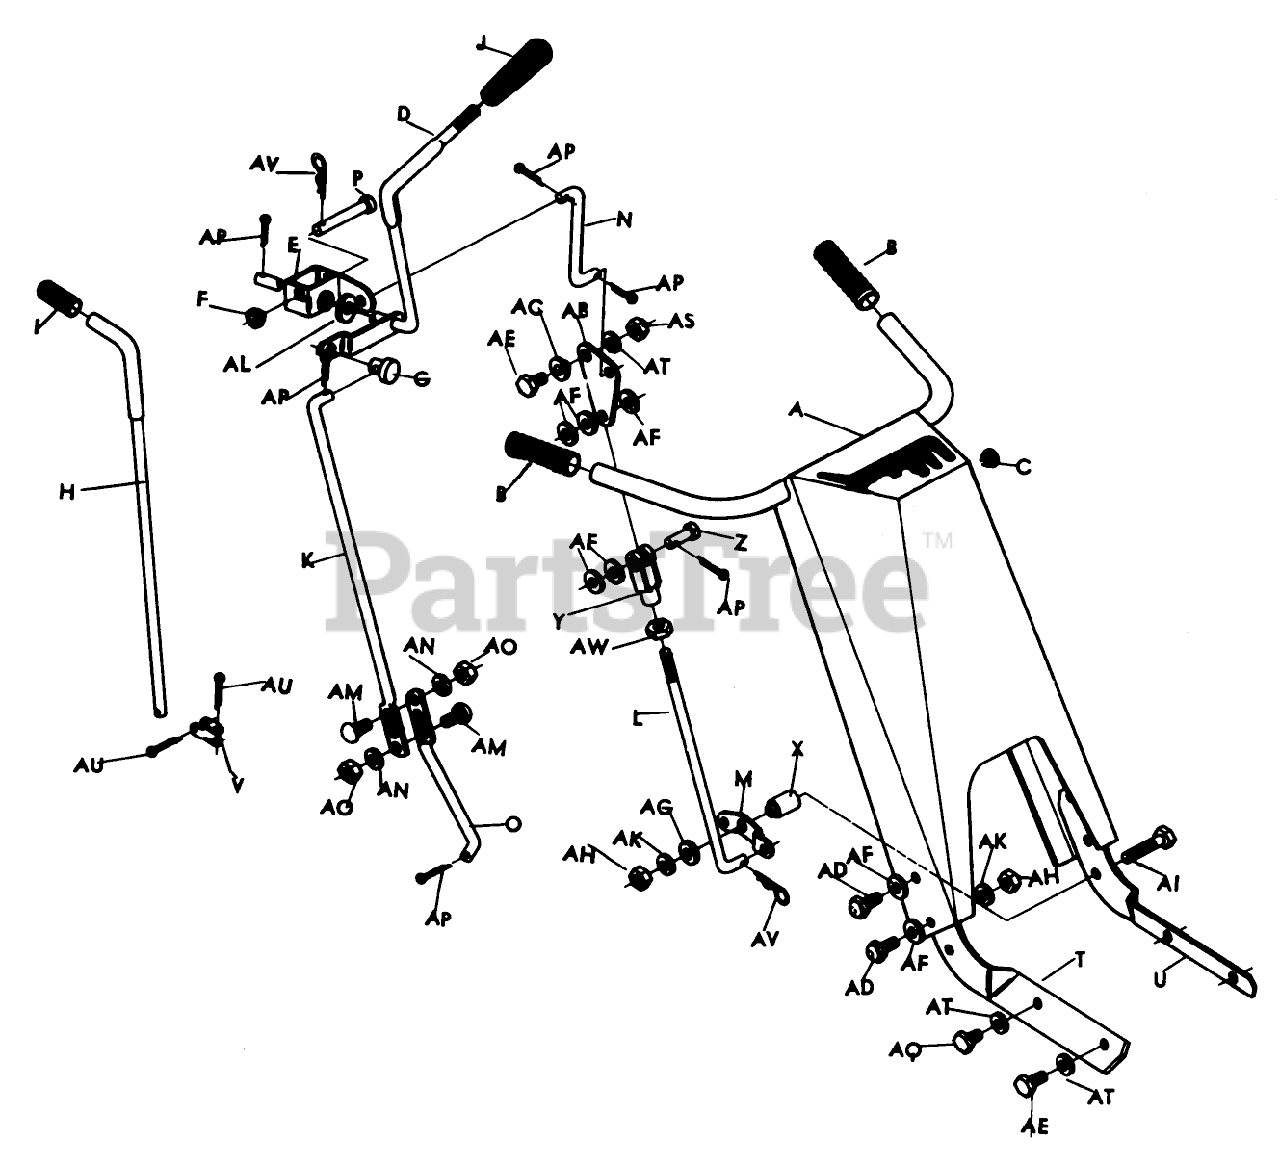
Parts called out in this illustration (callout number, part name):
A	Handle Bar Assembly
AE	5/16-18 x 1 Hex. Hd. Cap Screw, Pl.
AF	3/8 Flat Washer, Pl.
AG	5/16 Flat Washer, Pl.
AH	3/8-16 Hex. Nut, Pl.
AI	3/8-16 x 2 1/4 Hex. Hd. Cap Screw, Pl.
AK	3/8 Lock Washer, Pl.
AL	7/16 S.A.E. Flat Washer, Pl.
AM	1/4-20 x 3/4 Carriage Bolt, Pl.
AN	1/4 Lock Washer, Pl.
AO	1/4-20 Hex. Nut, Pl.
AP	1/8 x 3/4 Cotter Pin, Pl.
AQ	5/16-18 x 3/4 Hex. Hd. Cap Screw, Pl.
AS	5/16-18 Cone Lock Nut, Pl.
AT	5/16 Lock Washer, Pl.
AW	3/8-16 Hex. Jam Nut, Pl.
